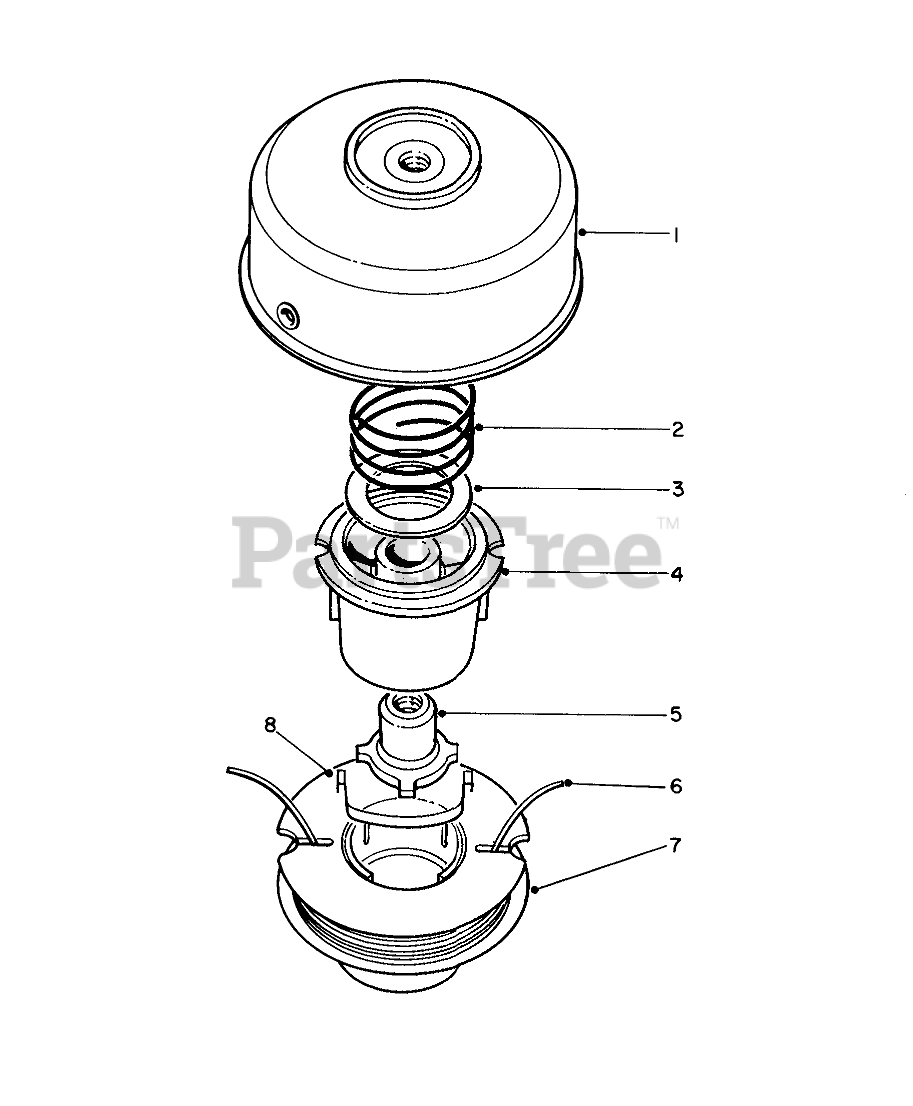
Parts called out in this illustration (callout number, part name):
1	ASM - TRIMMER DRUM & EYELET
2	SPRING
3	WASHER-FLAT
4	SPOOL CORE
5	LH DRIVER
6	REPL LINE PKG
7	Spool Housing
8	SADDLE-SPOOL CAP
